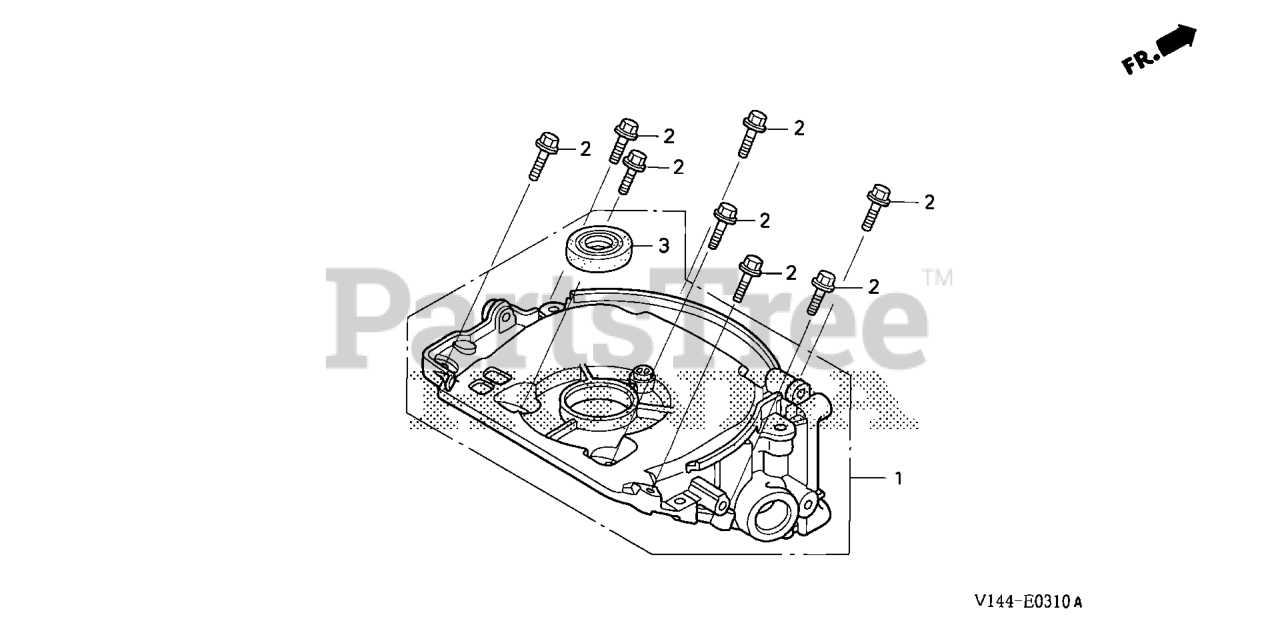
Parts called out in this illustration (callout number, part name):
1	CASE ASSY., OIL
2	BOLT, FLANGE (5X23)
3	OIL SEAL (17X27X5) (KOYO)
